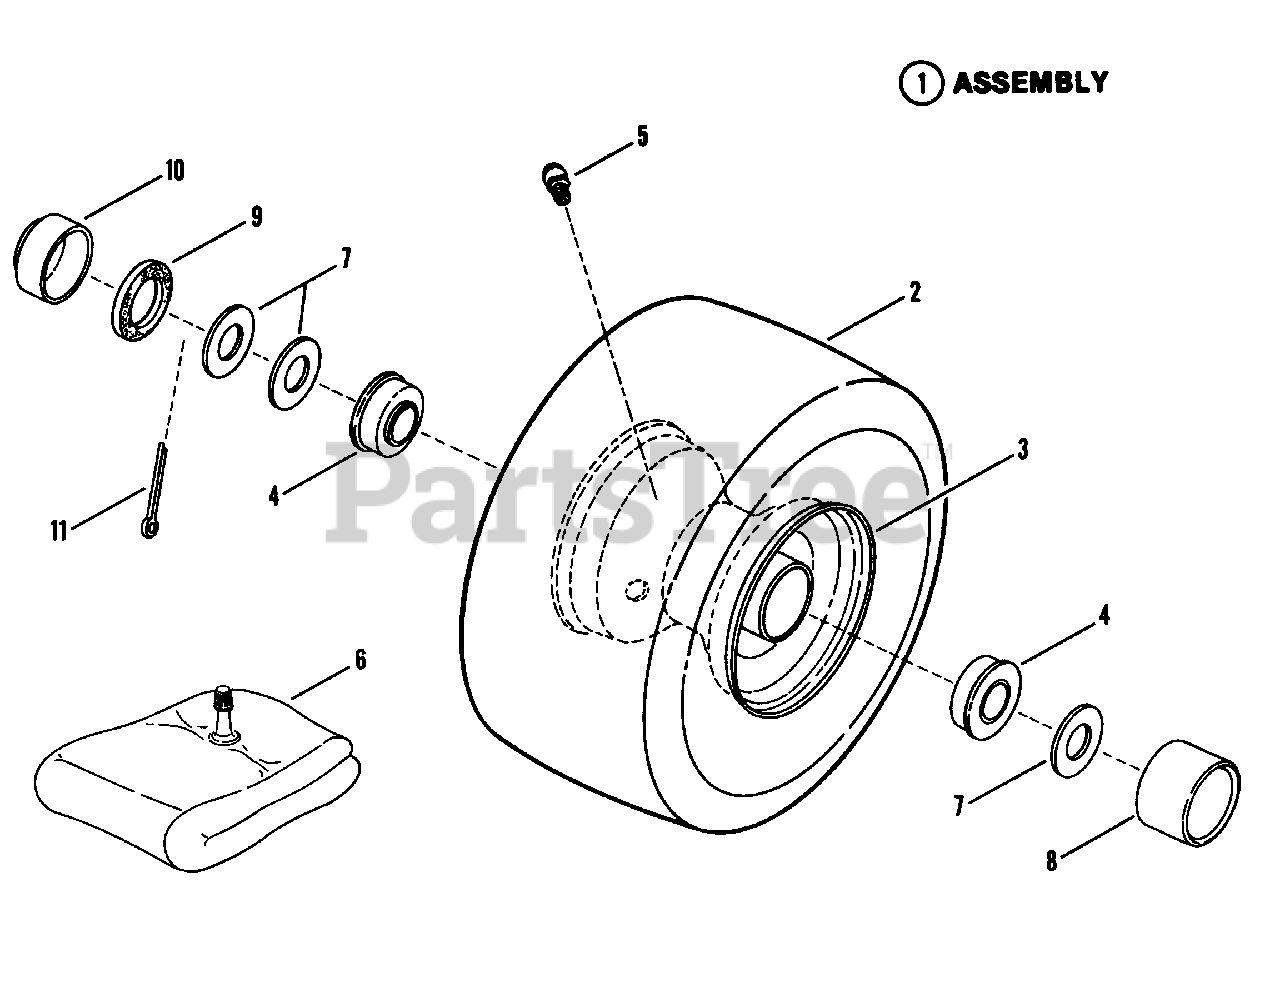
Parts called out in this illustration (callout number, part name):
1	ASSEMBLY, Tire & Rim
2	TIRE, 4.10/3.50x4
3	RIM, (For 4.10/3.50x4 Tire)
4	BEARING, Ball
5	FITTING, Lube
6	TUBE, Inner
7	WASHER,
8	HUB-CAP
9	SEAL, Felt
10	CAP, Dust
11	COTTER-PIN
